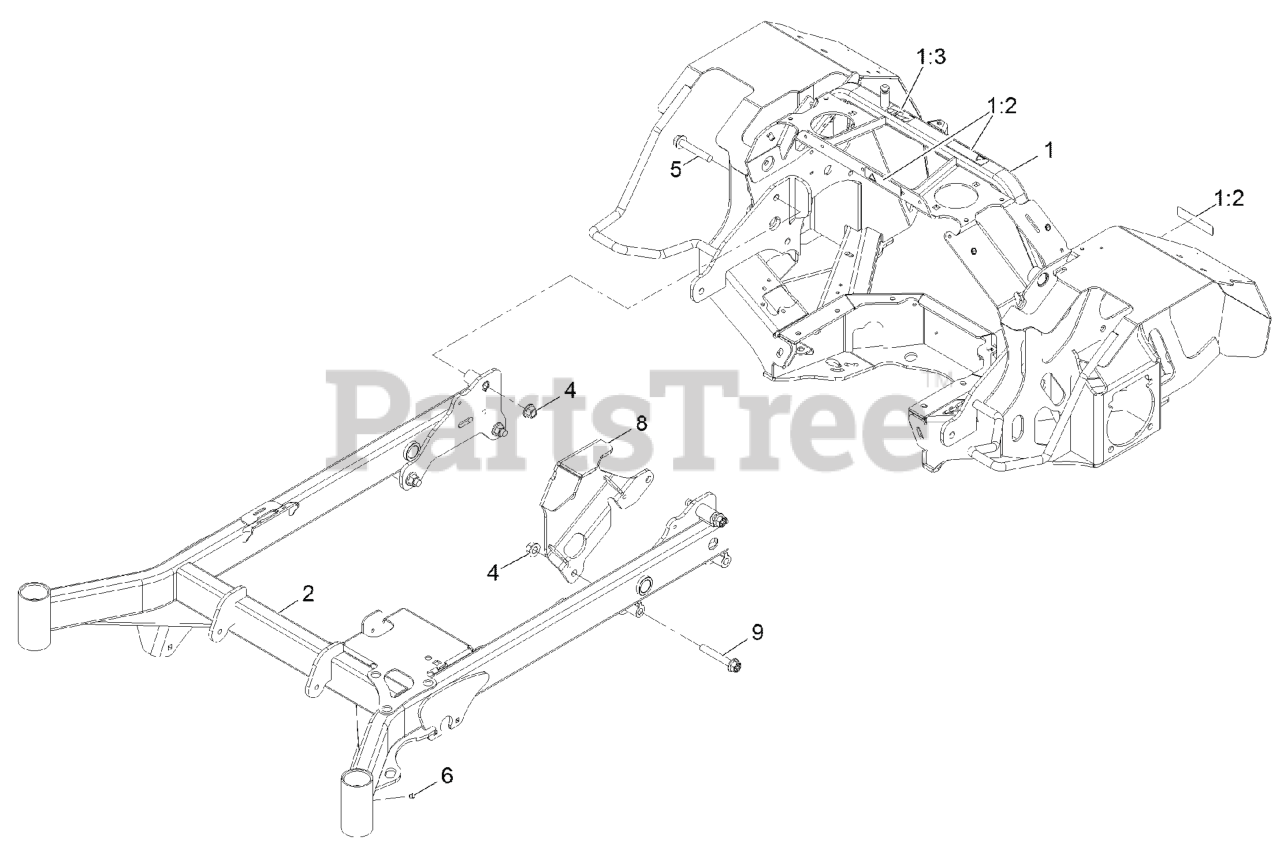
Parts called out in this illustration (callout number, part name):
1	ASM, REAR FRAME W/ DECALS
1:2	DECAL-WARNING
1:3	DECAL-BELT ROUTING HYD
2	WELD, FRONT FRAME, 48/52
4	Nut-Lock 1/2-13
5	SCREW-HF
8	WELD, FUEL MODULE
9	SCREW-HHF
